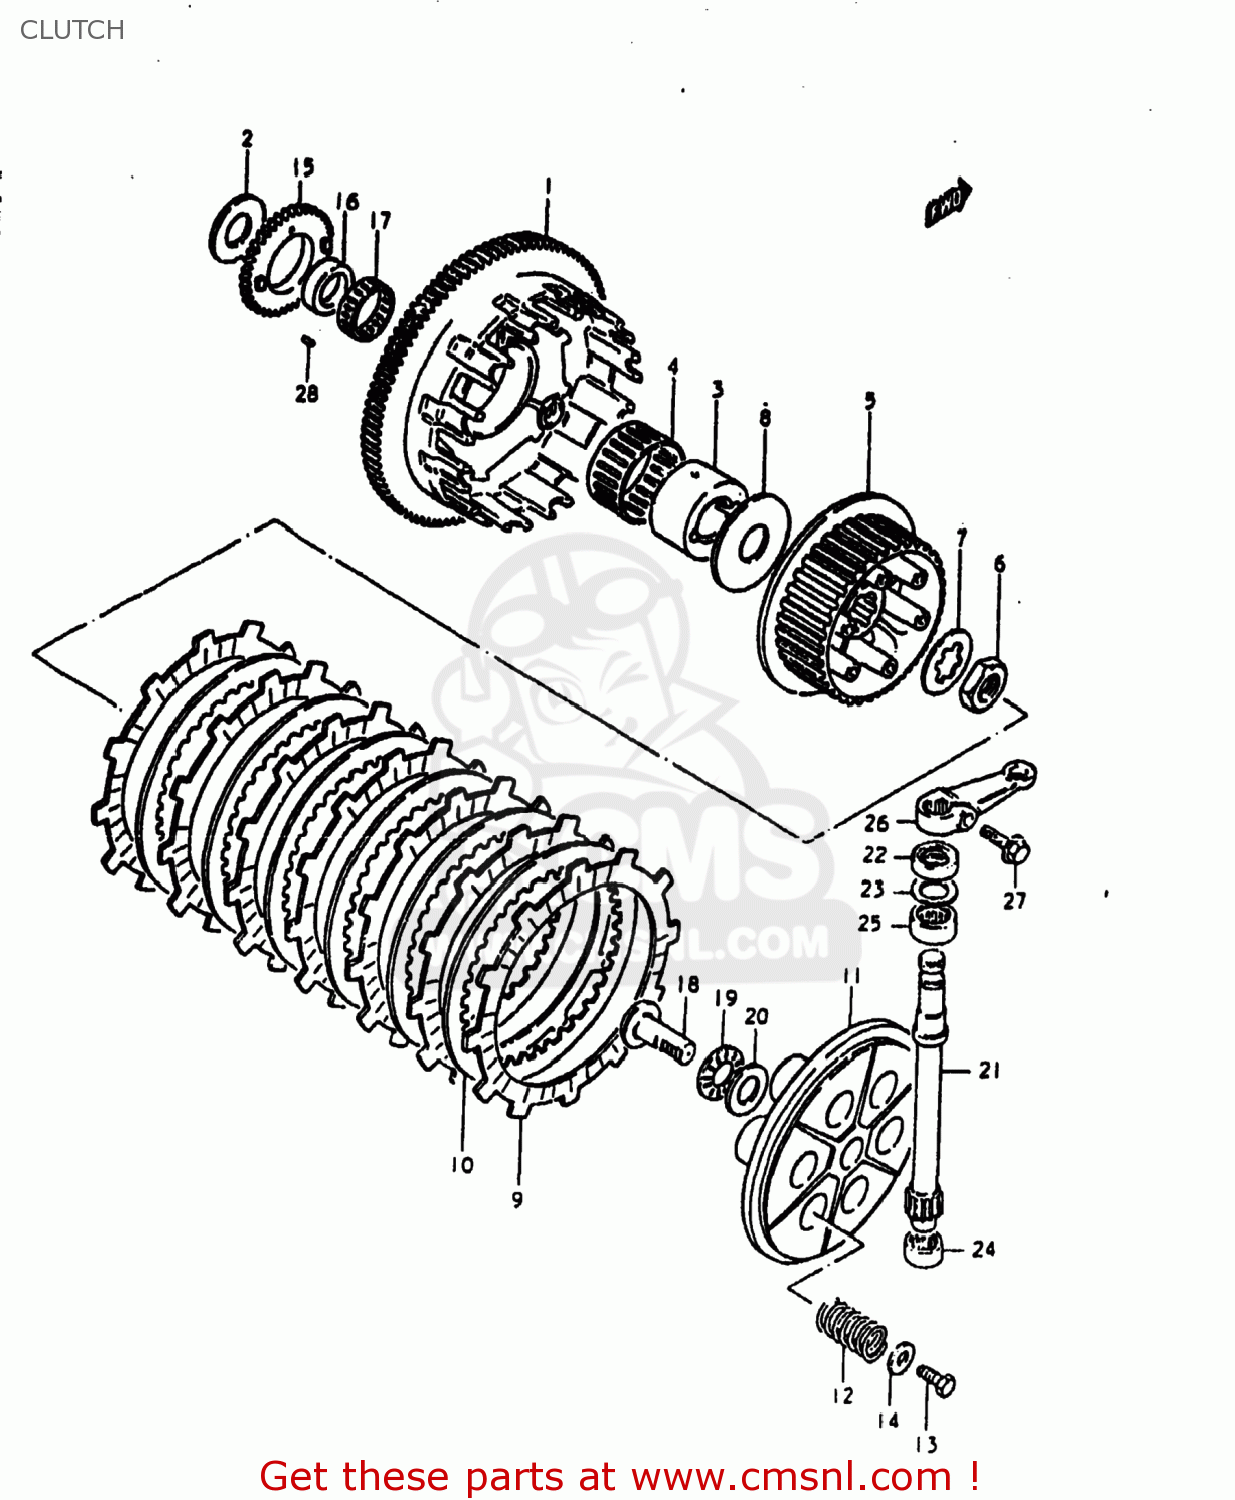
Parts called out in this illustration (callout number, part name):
1	GEAR ASSEMBLY,PRIMARY DRIVE
2	WASHER
3	SPACER,PRIMARY DRIVEN
4	BEARING
5	HUB,CLUTCH SLEEVE
6	NUT
7	WASHER,LOCK
8	WASHER(25X66X3.5)
9	PLATE,CLUTCH DRIVE (MCA)
10	PLATE,CLUTCH DRIVEN (NAS)
11	DISC,CLUTCH PRESSURE
12	SPRING
13	BOLT, UPPER
14	WASHER
15	GEAR,OIL PUMP DRIVE
16	SPACER,OIL PUMP DRIVE GEAR
17	BEARING(36X40X10)
18	RACK,CLUTCH RELEASE
19	BEARING(15X28X2)
20	WASHER
21	PINION,CLUTCH RELEASE
22	OIL SEAL
23	WASHER (14.2X22X1)
24	BEARING(12X19X12)
25	BEARING(15X22X12)
26	ARM,CLUTCH RELEASE
27	BOLT
28	CUSHION,PRIMARY DRIVEN GEAR
